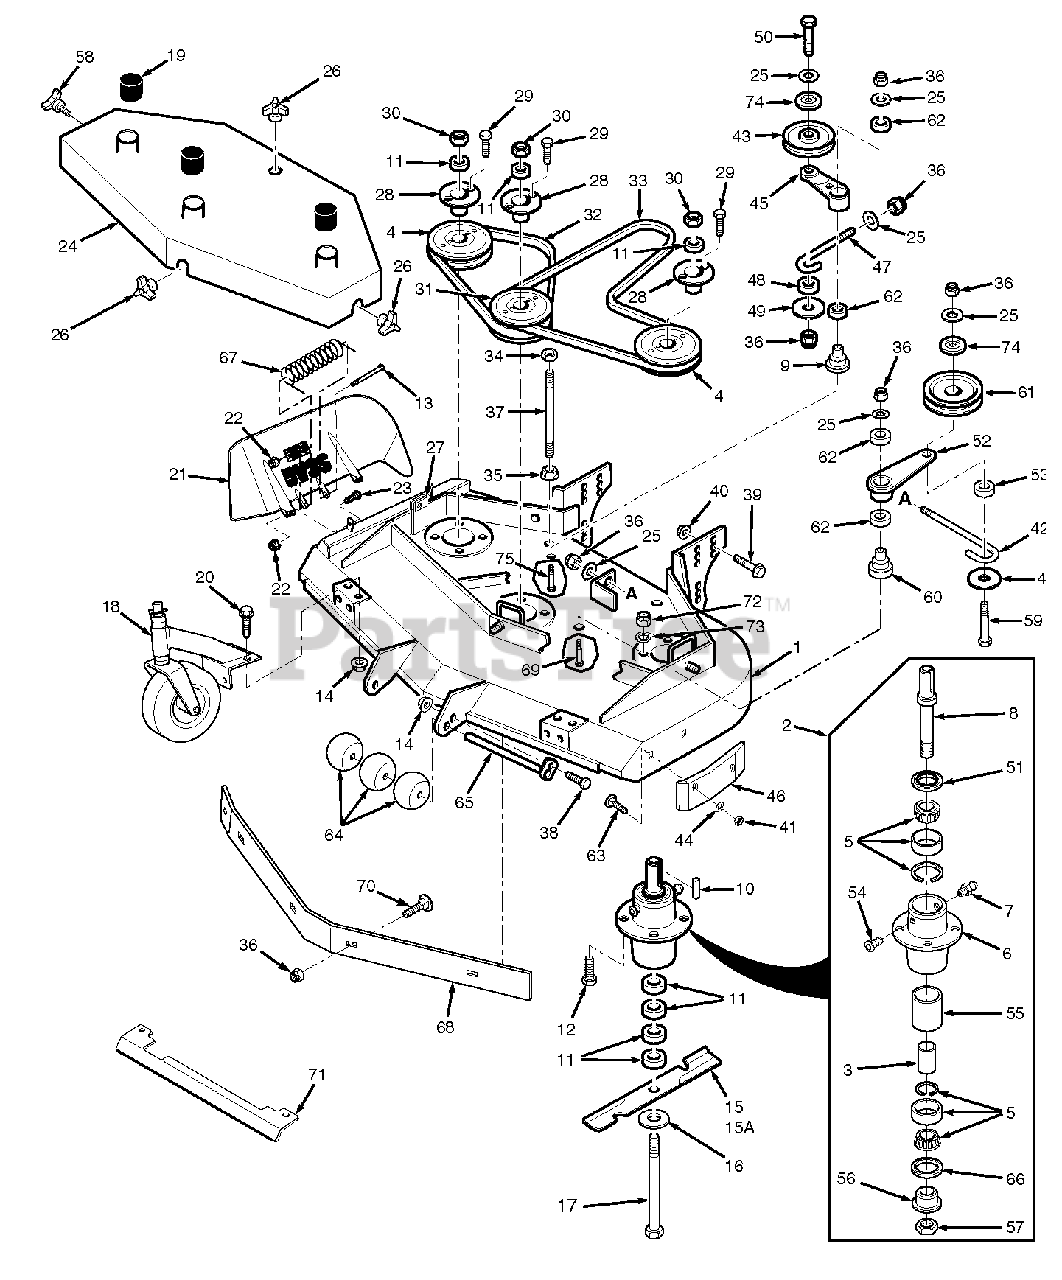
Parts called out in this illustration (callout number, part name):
1	Cutter Deck w/Decals
2	Spindle Assembly
3	Spacer, Inside
4	Pulley
5	Tapered Bearing
6	Spindle Housing
7	Grease Fitting Str. 5/16'
8	Spindle Shaft
9	Idler Pivot
10	Key, 1/4 x 1/4 x 2'
11	Spacer, Cutter Blade - Small
12	Bolt, 5/16-18 x 1-1/2' Hex Head
13	Bolt, 5/16-18 x 4-3/4' Hex Head
14	Serr. Flange Nut, 5/16-18
15	Cutter Blade 16-1/2'
15	Cutter Blade 18'
15A	Cutter Blade 16-1/2 Hi-Lift
15A	Cutter Blade 18 Hi-Lift
16	Flatwasher,5/8' (.688 x 1.75 x .134)
17	Hex Head Bolt, 5/8-11 x 9-1/2'
18	Caster Assembly
19	Cap, Spindle
20	Capscrew, 5/16-18 x 3/4'
21	Discharge Chute 48V
21	Discharge Chute 52V
22	Nut, 5/16-18 Elastic Elastic Stop
23	Bolt, 5/16-18 x 1-1/2' Hex Head
24	Belt Cover
25	Flat Washer, 3/8' Special
26	Wing Nut, 3/8-16 (Large)
27	U-Nut, 3/8-16
28	Tapered Hub
29	Bolt, 1/4-20 x 1' Hex Head
30	Nut, 5/8-11 Hex
31	Pulley, Double
32	Belt, RH Blade Drive
33	Belt, Blade Drive
34	Nut, 3/8-16, Nut Centerlock
35	Nut, 3/8-16, Serrated Flange
36	Nut, 3/8-16 Elastic Stop
37	Bolt, 5/16-18 x 1' Hex Head
38	Bolt, 5/16-18 x 1' Hex Head
39	Cpscrw, 1/2-13 x 1' Ser.Flg. HH
40	Nut, 1/2-13 Flange El. Stop
41	Hex Nut, 5/16-18 Center Locknut
42	J-Hook, 48V
42	J-Hook, 52V
43	Idler Pulley, 'V' Groove
44	Flatwasher, 5/16'
45	Idler Arm Assy.
46	Pad, Deck Wear
47	J-Rod, Idler Pulley
48	Spacer, J-Rod
49	Washer, 3/8 x 1-1/2 x 16 ga.
50	Bolt, 3/8-16 x 2-1/2' Hex Head
51	Seal, Cutter Spindle
52	Idler Arm Assy
53	Spacer, J-Rod
54	Reiief Fitting, Cutter Spindle
55	Spacer, Outside, Cutter Spindle
56	Spindle Bushing
57	Nut, Cutter Spindle
58	Knob, w/stud
59	Bolt, 3/8-16 x 3-3/4' Hex Head
60	Idler Pivot
61	Idler Pulley, Belt Clutch
62	Bearing
63	Bolt, Carriage 5/16-18 x 3/4'
64	Guide Roller
65	Roller Shaft
66	Seal, Cutter Spindle
67	Spring, Chute Return
68	Baffle Weldment 48V
68	Baffle Weldment 52V
69	Bolt, 3/8-16 x 3-1/4' Hex Head
70	Bolt, Carriage 3/8-16 x 1'
71	Heatshield
72	Nut, Hex Lock 5/16-18
73	Lock Washer 5/16'
74	Dust Shield
75	Bolt, 3/8-16 x 2-3/4' Hex Head
